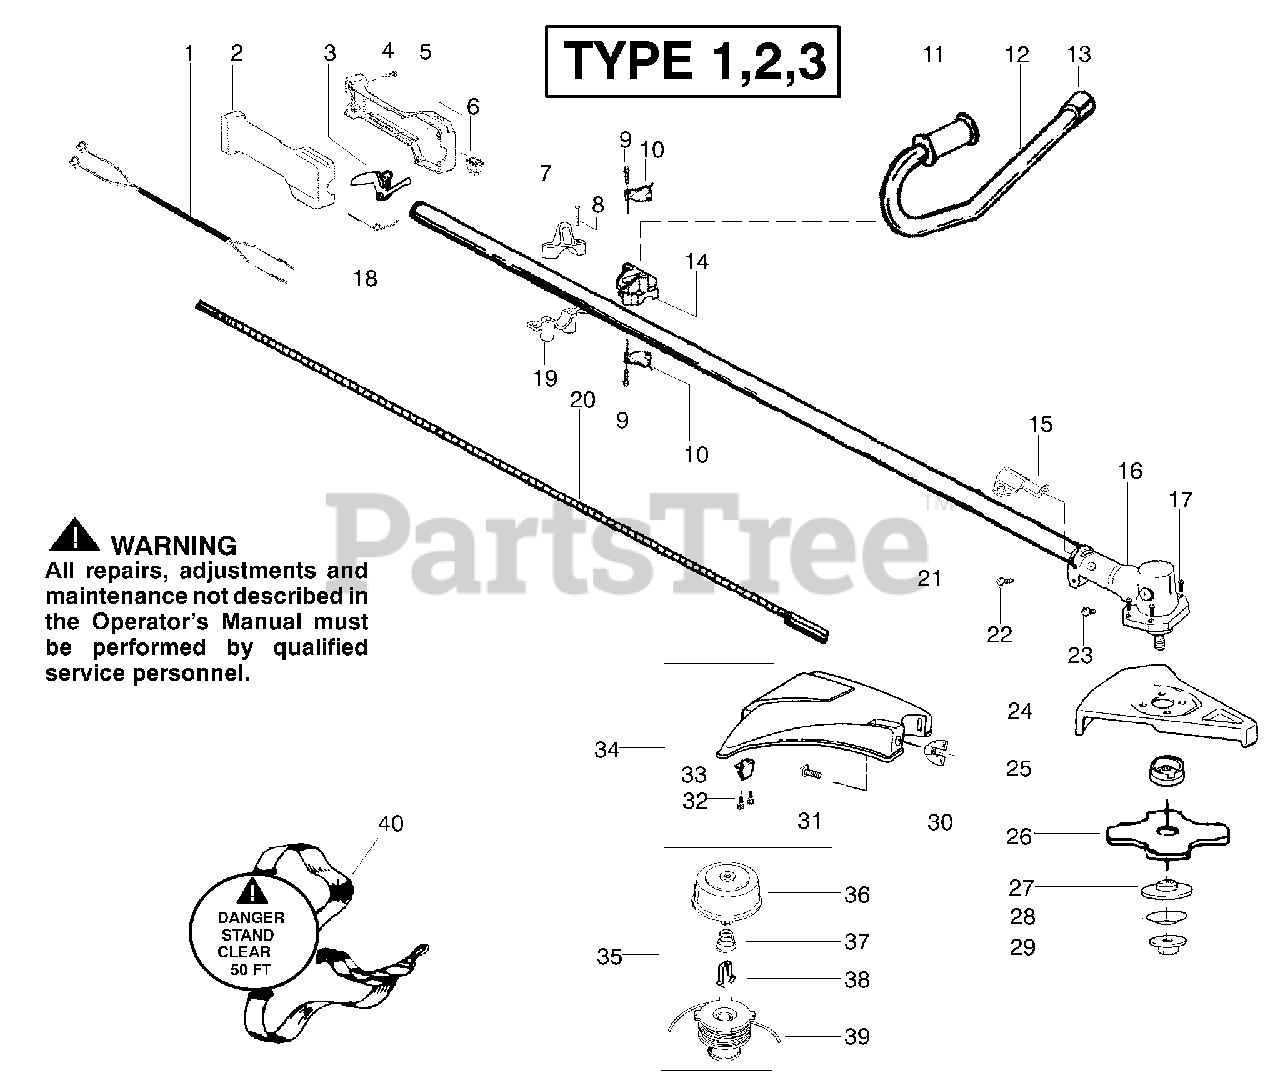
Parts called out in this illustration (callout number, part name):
1	Assy--Leadwire
2	Hsg.--Throttle Right
3	Lever--Throttle
5	Hsg.--Throttle Left
6	Kit--On/Off Switch
7	Clamp--Upper
10	Bracket--Handlebar
11	Grip--Handlebar
12	Kit--Handlebar Assy. w/decal
13	End Cap--Handlebar
14	Clamp--Handlebar
15	Bracket--Shield
16	Kit--Gear Box Ass'y.
18	Spring--lever return
19	Clamp--Lower
20	Shaft--Flex
21	Kit--Drive Shaft Assy
24	Kit--Metal Shield
25	Dust Cup
26	Accy--4 Point Blade
28	Washer--Belleville
29	Nut--Flange
30	Wingnut
32	Screw
33	Line Limiter
34	Kit--Shield Ass'y.
35	Accy--Cutting Head
36	Assy--Hub
37	Spring--Return
38	Retainer--Spool
39	Accy--Spool w/Line
40	Assy--Shoulder Strap
